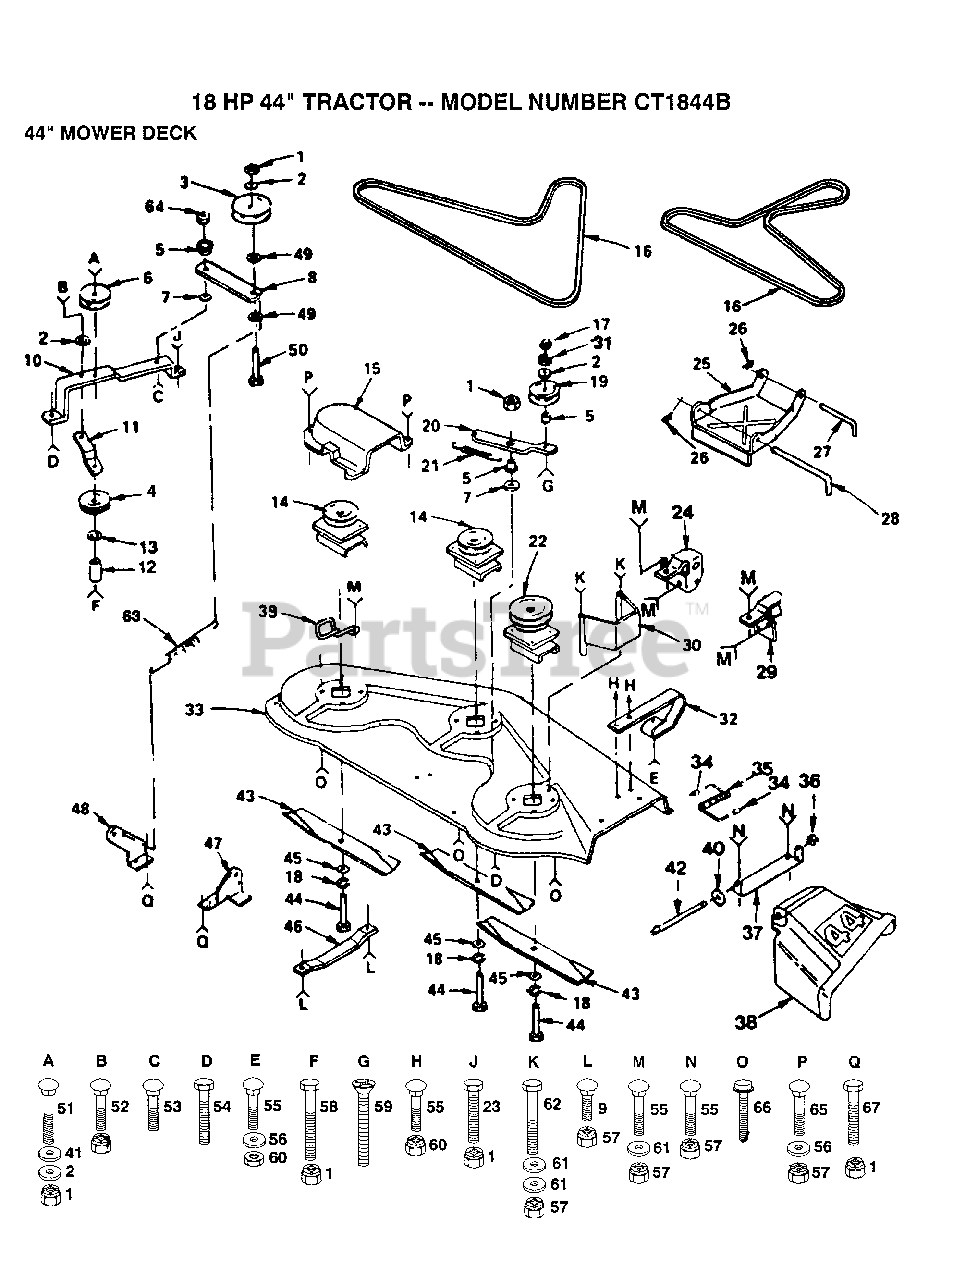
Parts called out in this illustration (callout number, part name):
2	WASHER
3	PULLEY IDLER
4	IDLER-FLAT T
5	SPACER RETAINER
6	IDLER-INSIDE T
7	"WASHER, WEAR LT"
8	ARM IDLER
9	BOLT
10	"SUPPORT YT, BAR"
11	BRACE-IDLER YT
12	SPACER
13	WASHER
15	GUARD YT
17	NUT.HEX.3/8-16UNC
19	IDLER.FLAT.GTV
20	ARM-IDLER YT
22	JACKSHAFT
23	BOLT
24	BRACKET LH YT
25	"STOP, LINK PARAL"
26	SPRING.RETAINER
27	"ROD, FRT. PARAL T"
28	HINGE PIN T
29	BRACKET RH YT
30	GUARD BELT HYT
31	LOCKWASHER
33	HOUSING MOWER
34	CAP-SLEEVE LT
36	NUT PUSH M
38	DEFLECTOR SHIELD
39	BELT RETIANER
40	WASHER
41	WASHER
42	ROD-HINGE T
44	BOLT.3/8-24X1-1/2
45	WASHER
46	RUNNER-LH M
47	BRKT SUSP REAR RH
48	BRKT SUSP REAR LH
49	WASHER
50	BOLT
51	BOLT
53	BOLT
55	BOLT
56	WASHER
58	BOLT - HEX 3/8 - 16 X 3
59	SCREW YT
61	WASHER M
62	BOLT
63	"SPRING.EXT.8.5"""
64	LOCKNUT
66	SCREW
67	BOLT
